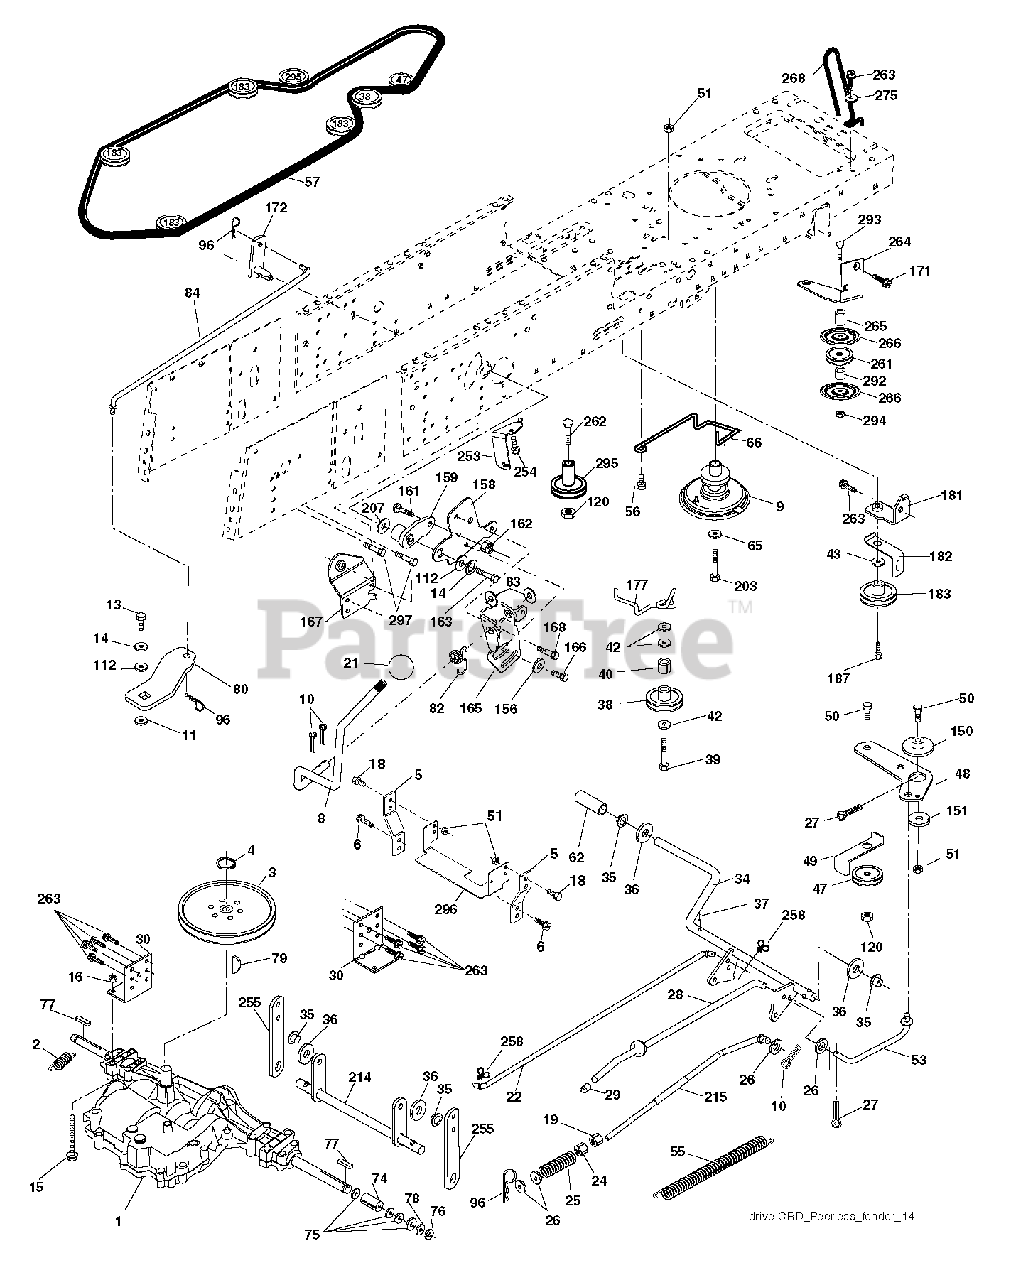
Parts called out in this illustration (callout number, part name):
1	Husqvarna TBD
2	SPRING,BRAKE RETURN
3	PULLEY
4	RETAINING RING LT
5	STRAP TORQUE
6	SCREW 5/16"
8	ROD SHIFT FENDER ADJUST LT
10	PIN COTTER
11	WASH-SHFT PLT LT
13	BOLT 1/4-28X3/4
14	LOCKWASHER
15	BOLT HEX 5/16-18 GR 5
16	NUT.71038.31-18.HEX.NYLOCK
18	BOLT
19	NUT
21	KNOB T (1/2-HOLE)
22	ROD
24	NUT
25	SPRING ROD LT
26	WASHER
27	COTTER PIN
28	ROD, PARKING BRAKE
29	PLUNGER CAP
30	Transaxle Bracket
34	SHAFT, FOOT PEDAL
35	BEARING.NYLON
36	WASHER LT
37	DRIVE PIN
38	PULLEY.FLAT
42	WASHER
43	WASHER T
47	IDLER PULLEY
48	BELLCRANK, CLUTCH
49	RETAIN BELT
50	BOLT.3/8-16X1.50
53	LINK.CLUTCH.7.66.2005
55	SPRING, RETURN LT
56	SCREW.3/8-16
57	V-BELT.KEV.111"
62	PEDAL COVER T
65	LOCKWASHER
66	KEEPER BELT ENGINE
74	SPACER AXLE
77	SQUARE KEY
79	KEY.WOODRUFF
82	SHIFT SPRING
83	WASHER
96	RETAINER M
112	WASHER LT
120	NUT LOCK FLG 3/8-16 UNC
150	BUSHING.BELLCRANK.GRD.DR
151	WASHER 12/32X2X10GA
156	WASHER.SRRTD.5/16
158	BRACKET
159	RB HUB.SHIFT
161	BOLT
162	NUT.CROWNLOCK.1/4
163	BOLT
165	RP BRACKET
166	CAPSCREW.HXHD.FLG.5/16-18X.625
167	BRACKET.SUPT.SHIFT.CRD
168	BOLT.SHOULDER.5/16-18X
171	SCREW LT
172	SHAFT
181	BRACKET
182	BELT GUIDE
183	PULLEY.V-IDLER.
187	BOLT.5/16-18X1.25
203	BOLT.HEX.7/16-20 X 5
207	WASHER NYL
214	LEVER
254	SCREW 3/8-16X1
255	SHAFT
258	CLIP RETAINER
261	FLAT IDLER PULLEY
263	SCREW, 3/8-16X3/4
264	BRACKET.IDLER.CHASS.NORAM.2010
265	SPACER
266	PROTECTOR
268	GUARD MUFFLER
275	WASHER
293	BOLT.RDHD SQNK 3/8-16 X 3-1/2
294	Hex Nut, 3/8-16
295	PULLEY IDLER COMPOSITE
297	SCREW LT.3/8-46X5/8
